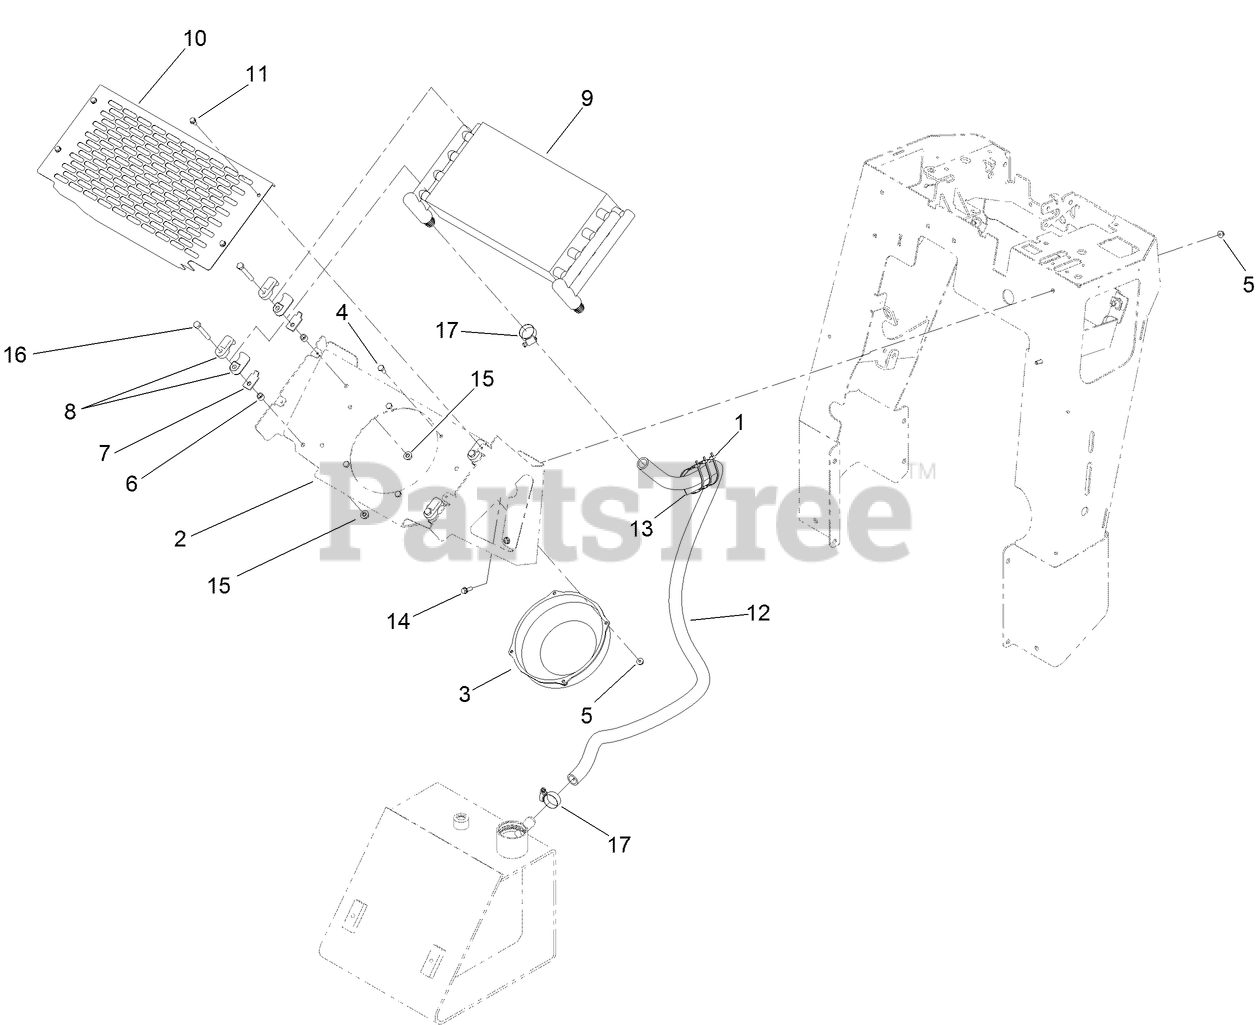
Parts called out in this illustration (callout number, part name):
1	TIE-CABLE
2	MOUNT-COOLER
4	SCREW-HH
5	NUT-HF
6	Spacer-Tube
7	PLATE-SUPPORT, CLAMP
9	COOLER-OIL
10	COVER-COOLER
11	SCREW-HWH
12	HOSE-COOLER
13	PROTECTOR-HOSE
14	SCREW-HHF
15	NUT-HF, NI
16	SCREW-HH
17	CLAMP-HOSE
